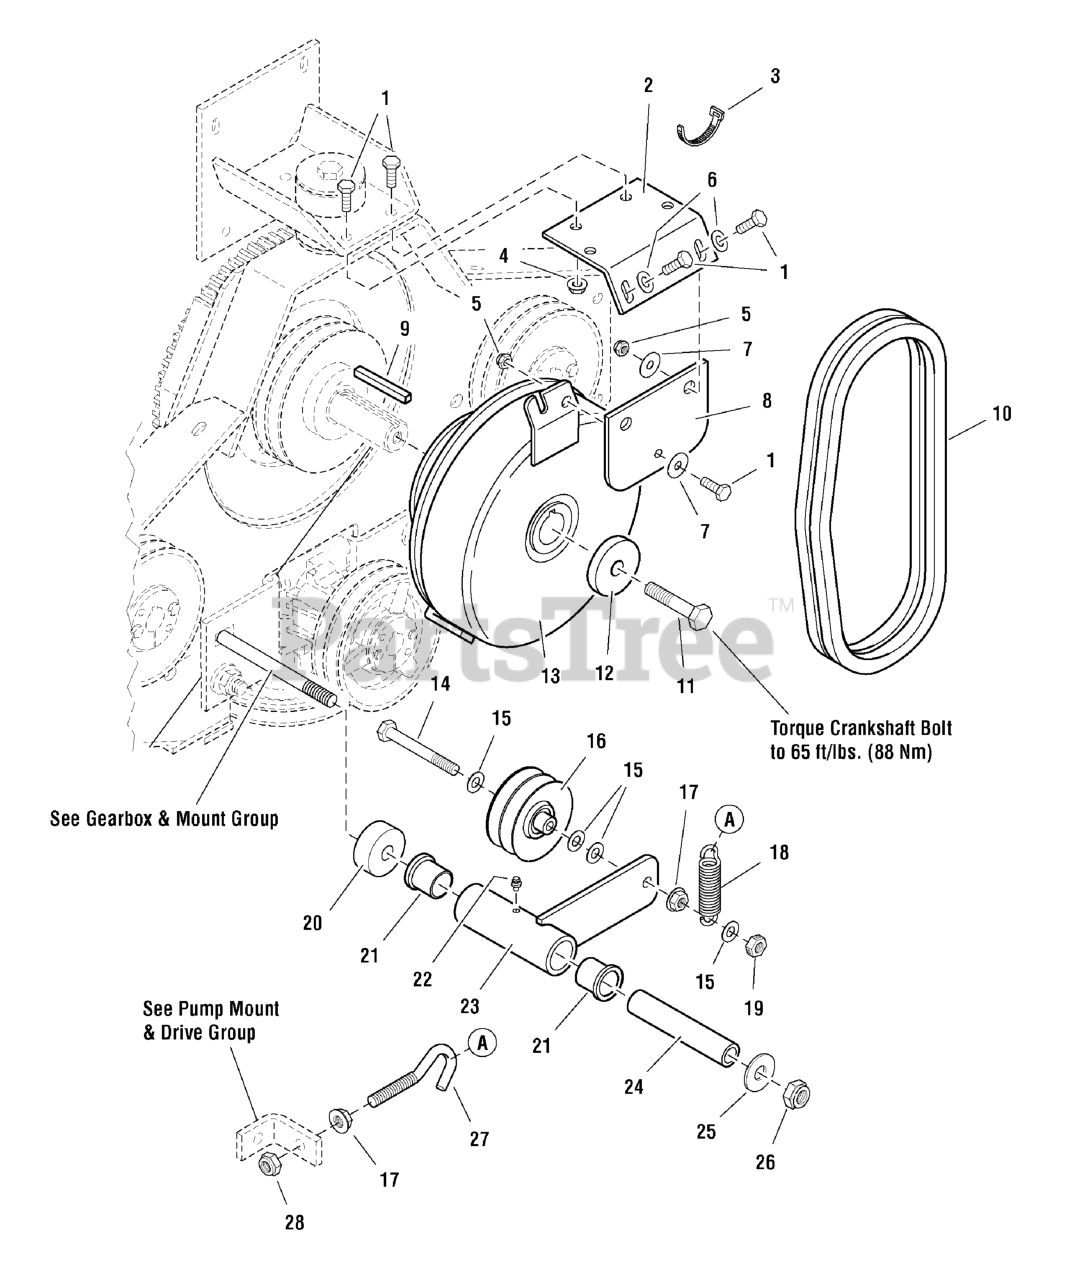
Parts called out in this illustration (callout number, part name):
1	BOLT, 5/16-18 X 1 GD5 YZ
2	CLUTCH ANCHOR
3	TIE WRAP, 5-1/2"
4	NUT, 5/16-18 HEX SERRATED FLANGE (SMALL)
5	NUT, 5/16-24 HEX NYLON LOCK
6	WASHER, 5/16" SAE
7	WASHER, Clutch Anchor
8	CLUTCH ANCHOR PAD
9	KEY, 1/4 SQ. X 3
10	BELT, Clutch Drive (set of 2)
11	CRANKSHAFT BOLT, 7/16 x 1-1/2
12	SPACER, .45 x 1.88 x .38
14	BOLT, 3/8-16 X 3" GD5 CZ
15	WASHER, 3/8 SAE
16	PULLEY, Idler
17	NUT, 3/8-16 Hex Serrated Flange
18	SPRING, Extension
19	NUT, 3/8-16 Hex Side Lock
20	SPACER, .51 x 1.75 x .75
21	BUSHING, Flange
22	GREASE FITTING
23	CLUTCH DRIVE IDLER ARM
24	PIVOT SLEEVE, Long
25	WASHER, 1/2 SAE
26	NUT, 1/2-13 HEX NYLON LOCK
27	SCREW HOOK, 3/8-16 x 4-1/4
28	NUT, 3/8-16 HEX NYLON LOCK
